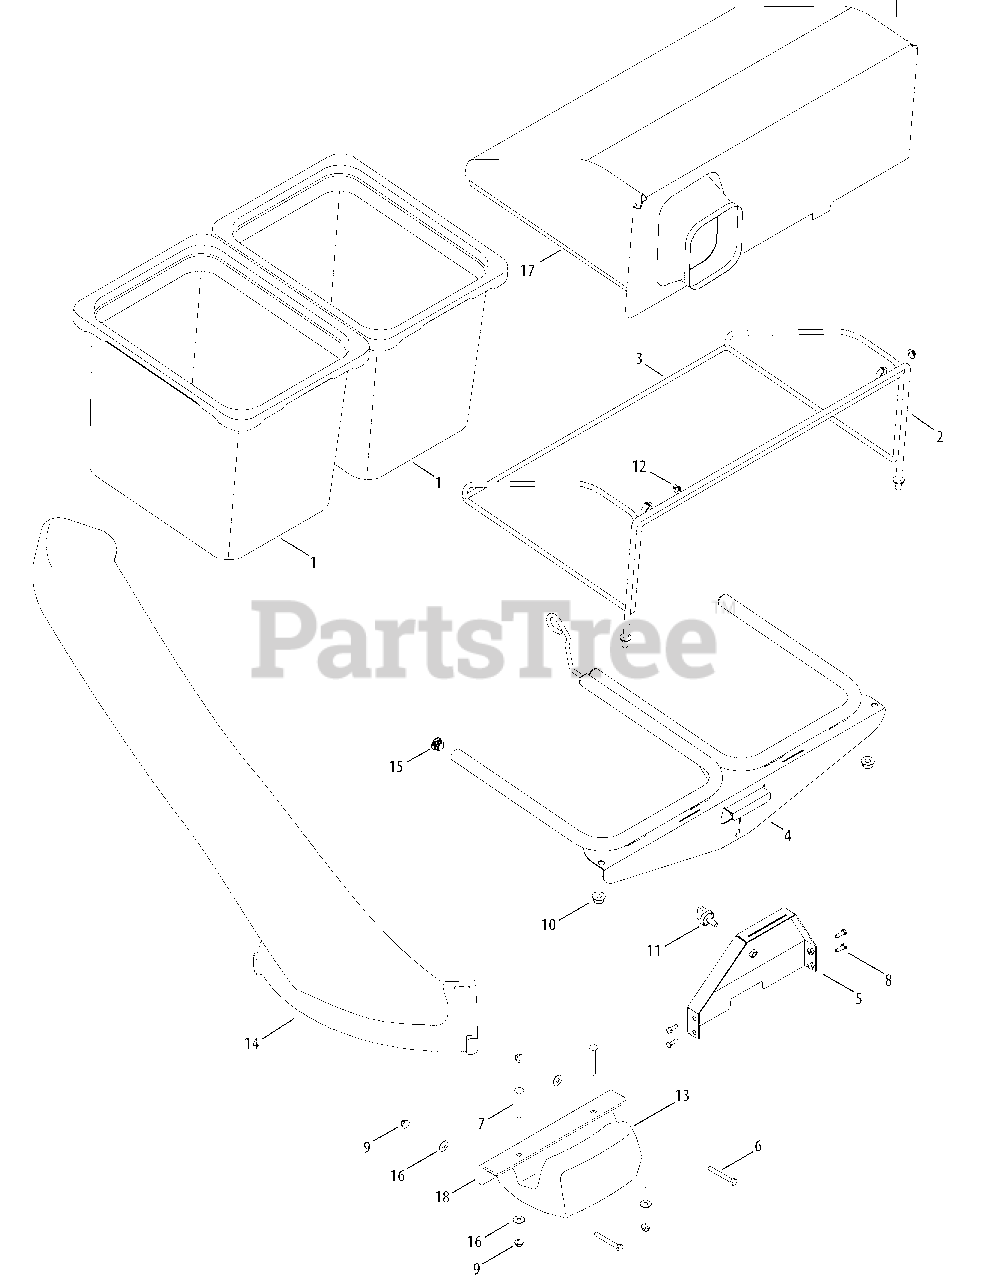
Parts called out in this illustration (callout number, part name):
2	Front Hood Assembly Frame
3	Rear Hood Assembly Frame
4	Bagger Support Assembly
5	Mounting Bracket
6	Hex Lock Screw, 5/16-18, 2.50
7	Carriage Bolt, 5/16-18, 2.50
8	Hex Head Screw, 5/16-18, .750
9	Flange Lock Nut, 5/16-18
10	Flange Lock Nut, 1/2-13
11	Knob, 3/8-16, .875
12	Push Cap, 3/8 Rod
14	Chute Tube
16	Flat Washer, .349 x .879 x .063
17	Grass Catcher Hood
18	Weight Mounting Bracket
